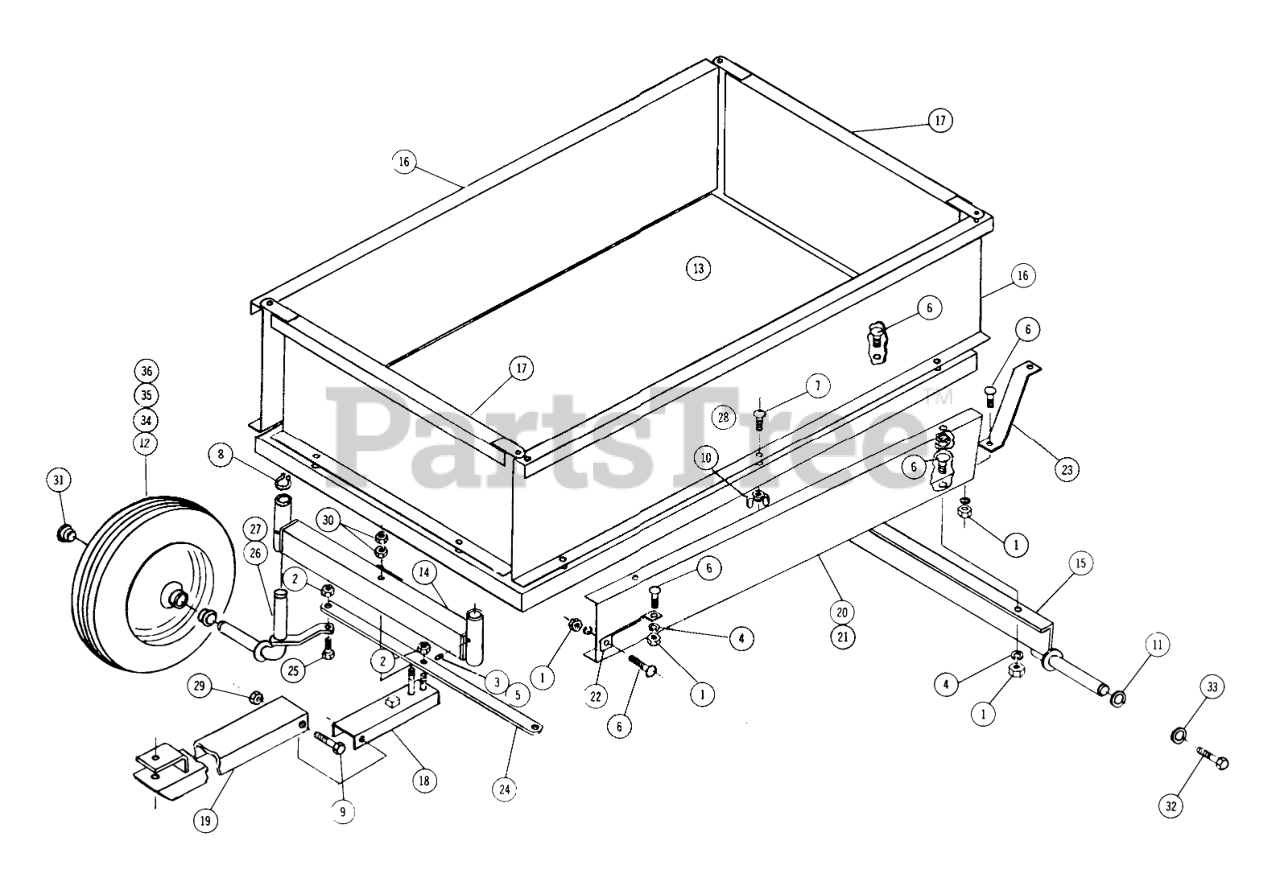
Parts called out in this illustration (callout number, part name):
1	Nut
2	Jam Nut
3	Zerk
4	LOCKWASHER
5	Washer (Grease Fitting)
6	Bolt-Carriage
7	Carriage Bolt
8	E-RING
9	HEX HD CAP SCREW
10	Wing Nut 3/8-16
11	WASHER
12	Tire & Wheel
13	Bed
14	Front Axle Assembly
15	Rear Axle Assembly
16	Side Panel
17	End Panel
18	Swivel Hitch Assembly
19	Draw Bar Assembly
20	Clip
21	Bed Support L.H.
22	Front Brace
23	Rear Brace
24	Tie Rod
25	Clevis Pin
26	Spindle Assembly R.H.
27	Spindle Assembly L.H.
28	Decal
29	Eslok Nut
30	Jam Nut 5/8-11
31	BEARING
32	Bolt
33	WASHER
34	Tire
35	Tube
36	Wheel
